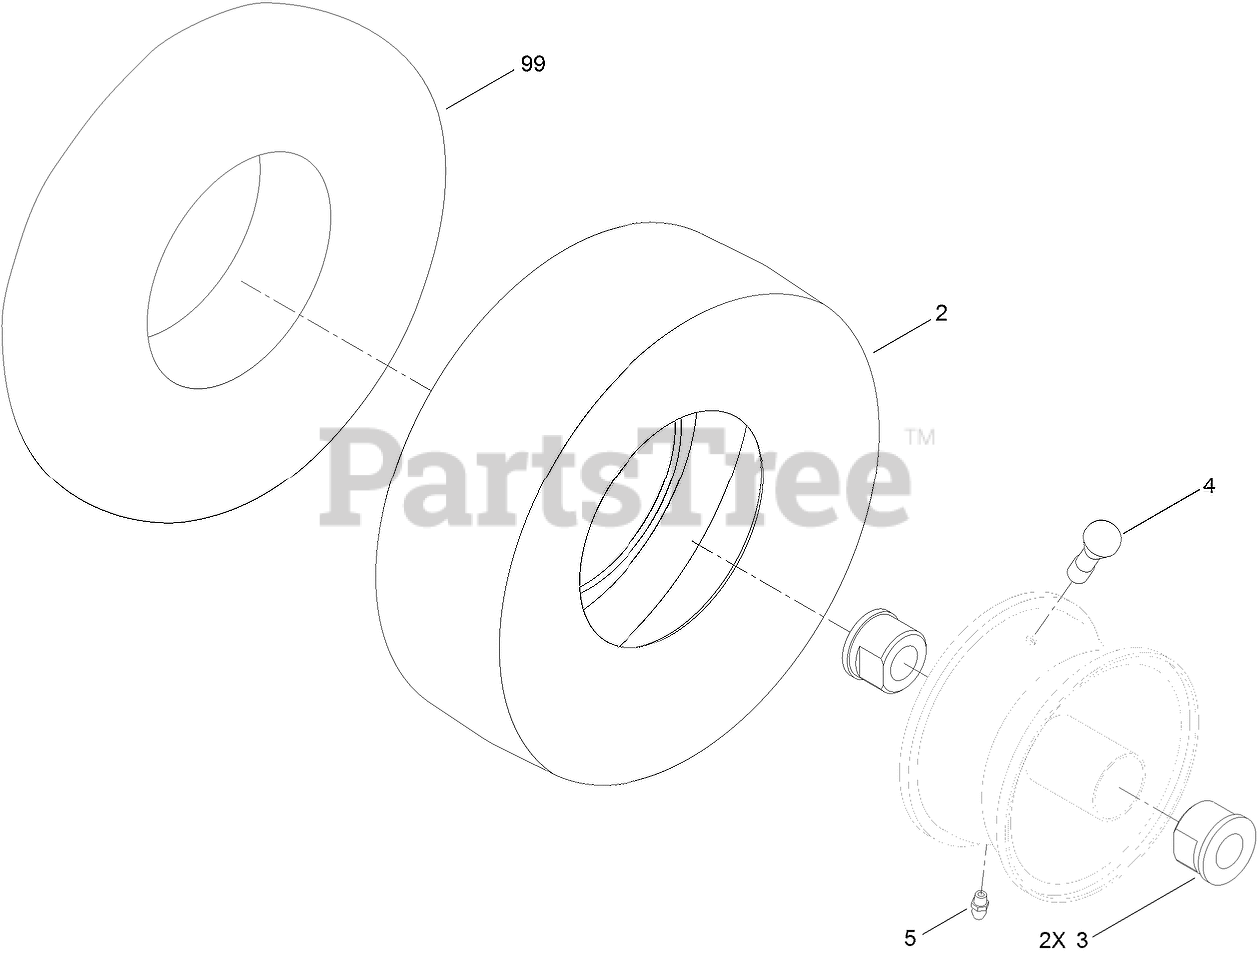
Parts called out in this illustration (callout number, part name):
2	TIRE-SMOOTH
3	BUSHING-FLANGE
4	STEM-VALVE
5	FITTING-GREASE
99	TUBE-INNER
